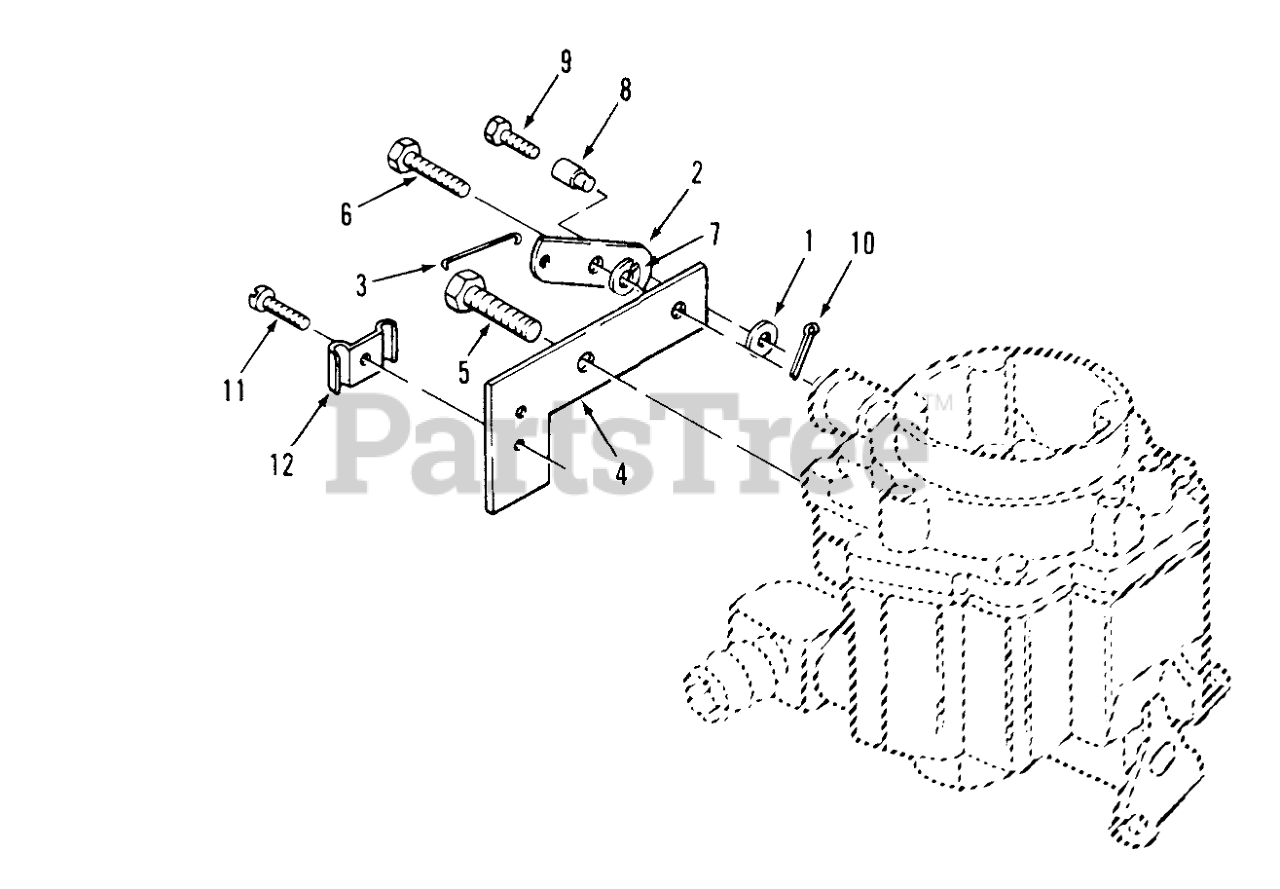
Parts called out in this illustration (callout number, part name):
1	Washer
2	SWIVEL-CHOKE
3	LINK-CHOKE
4	BRACKET
5	SCREW-HWH
6	BOLT-SHOULDER
7	WASHER-LOCK
8	SWIVEL
9	SCREW
10	PIN-COTTER
11	SCREW-TAPPING
